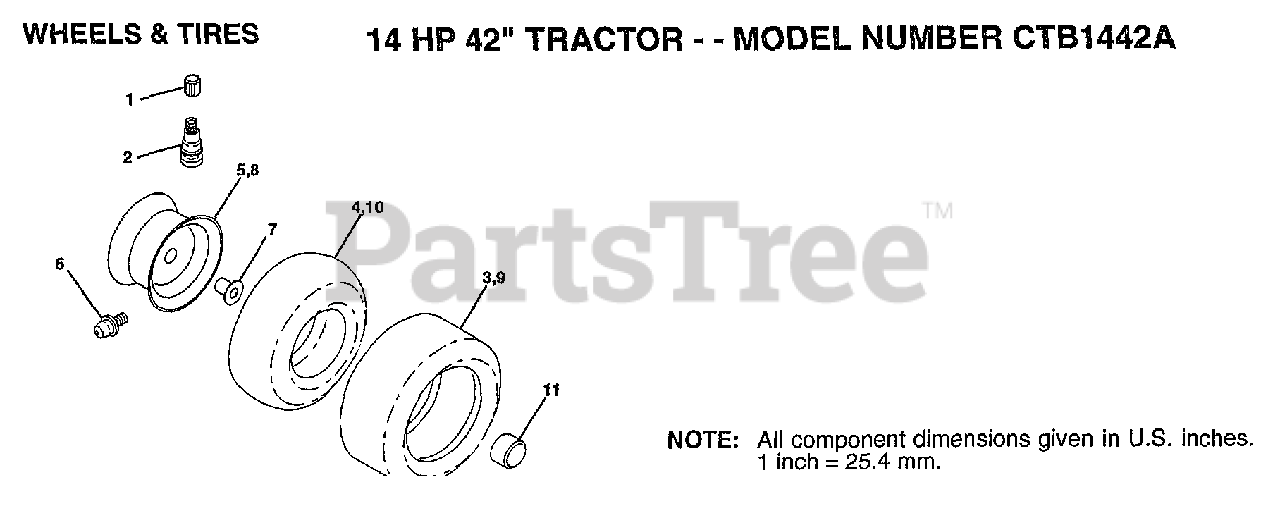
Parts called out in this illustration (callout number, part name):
1	VALVE CAP
2	VALVE STEM LT
4	TUBE.5.3/4.5/6
6	FITTING LT
7	"FLANGE, BEARING"
9	TIRE.20X8-8
10	TUBE.18X9.5-8
11	HUB CAP
